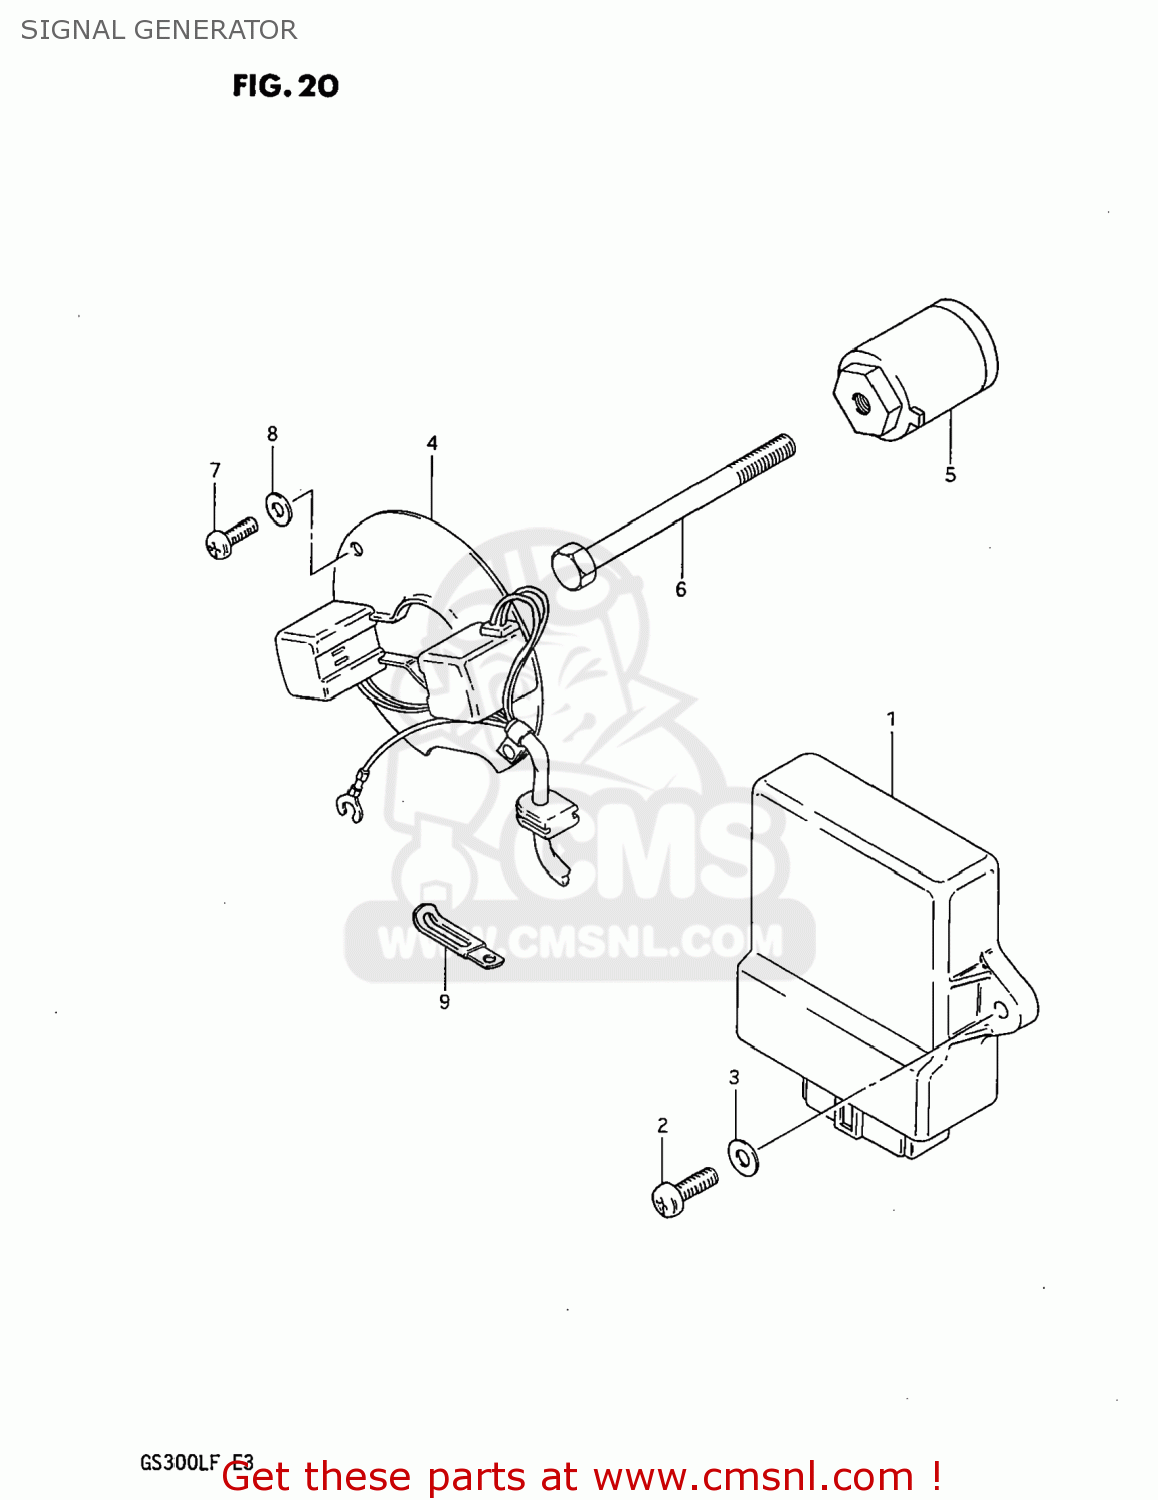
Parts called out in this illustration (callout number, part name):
1	IGNITER UNIT ASSEMBLY
2	SCREW
3	WASHER
4	SIGNAL GENERATOR ASSEMBLY
5	ROTOR,SIGNAL
6	BOLT
7	SCREW(5X12)
8	WASHER(5.5X10X0.8)
9	CLAMP L:35
